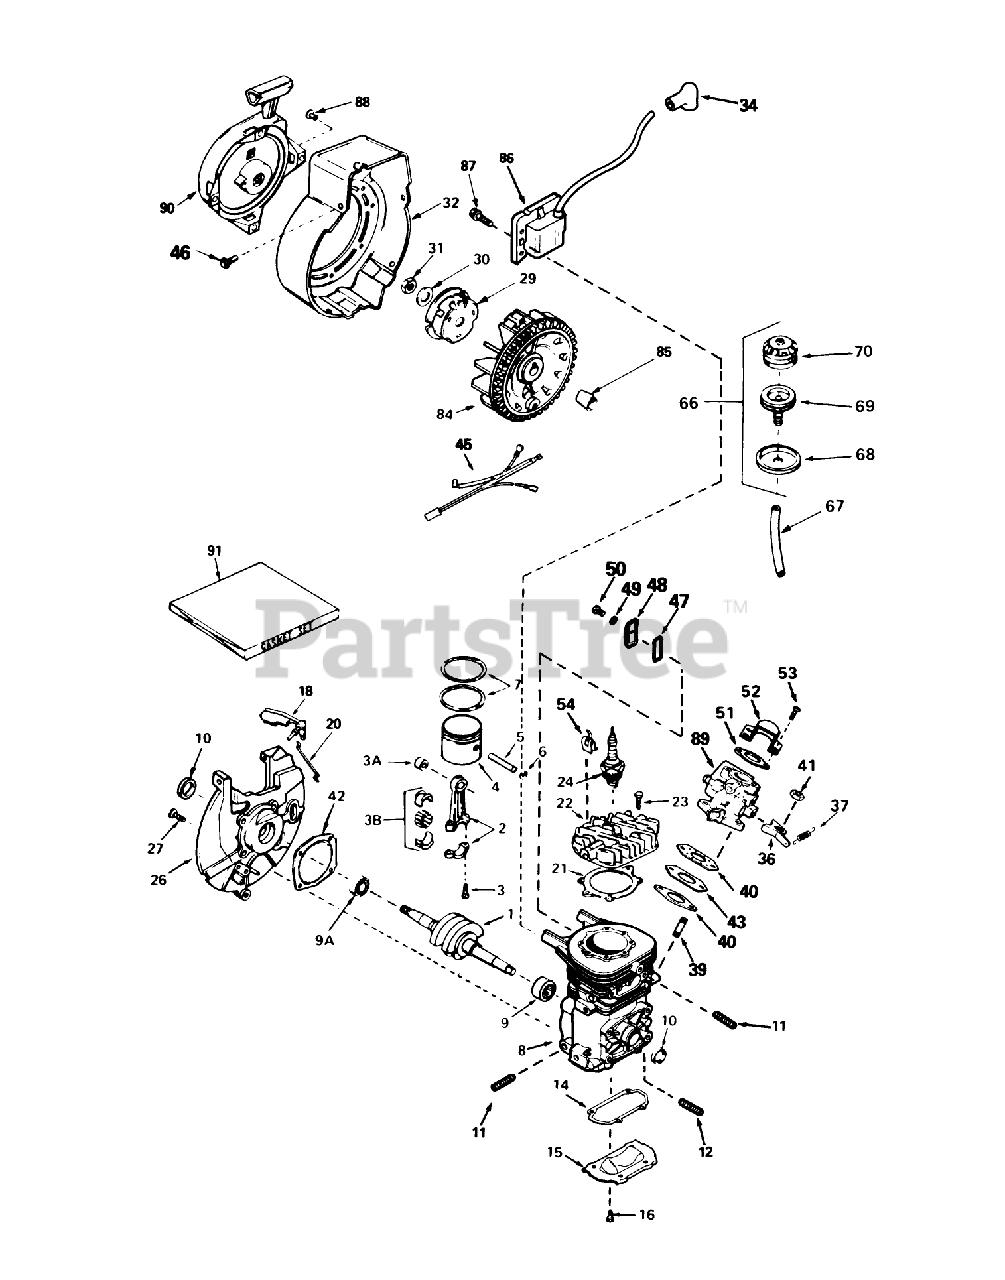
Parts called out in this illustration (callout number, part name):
1	Crankshaft
2	Rod Assy., Connecting (Incl. Ref. #2, 3 4)
3	Bolt-Rod, Connecting
3A	Bearing-Cartridge
3B	Bearing Liner Set-Needle
4	Piston
5	Pin-Piston
6	Ring-Retaning
7	Ring Set
8	Block Assy., Cylinder (Order short block if replacement is required)
9	Bearing-Cartridge
9A	Bearing-Ball
10	Seal-Oil
14	Cover
15	Plate-Cover
16	Screw (T-25, 10-24 x 1/2)
18	Vane Assy., Air
20	Link-Governor
21	Gasket, Head
23	Screw (T-30, 1/4-20 x 3/4)
24	Spark Plug-Resistor (R C J 8Y)
26	Base Assy.-Blower Housing (Incl. Ref. #10)
27	Screw (1/4-20x19/32)
29	Cup-Starter
30	Washer-Spring
31	Nut-Flywheel
32	Housing-Blower
34	Cover-Spark Plug
36	Lever-Adjusting, Rpm
37	Spring-Governor
40	Gasket-Carburetor
41	Locknut
42	Gasket, Shroud Base
43	Spacer
45	Harness-Wire
46	Screw-Hex, Hd.
47	Gasket-Cover
48	Comp. Release Cover
49	Washer
50	Screw (T-25, 10-24 x 1/2)
51	Gasket
52	Baffle-Carburetor
53	Screw
66	Primer Assy.
67	Line, Primer
68	Retainer, Primer Bulb
69	Body, Primer
70	Bulb-Primer
84	FIywheel
85	Blade (20 inch)
86	Solid State
87	Screw
88	Rivet, Pop (3/16" dia.) (Can be purchased locally)
89	Carburetor (Incl. Ref. #40)
90	Starter-Rewind
91	Gasket Set
